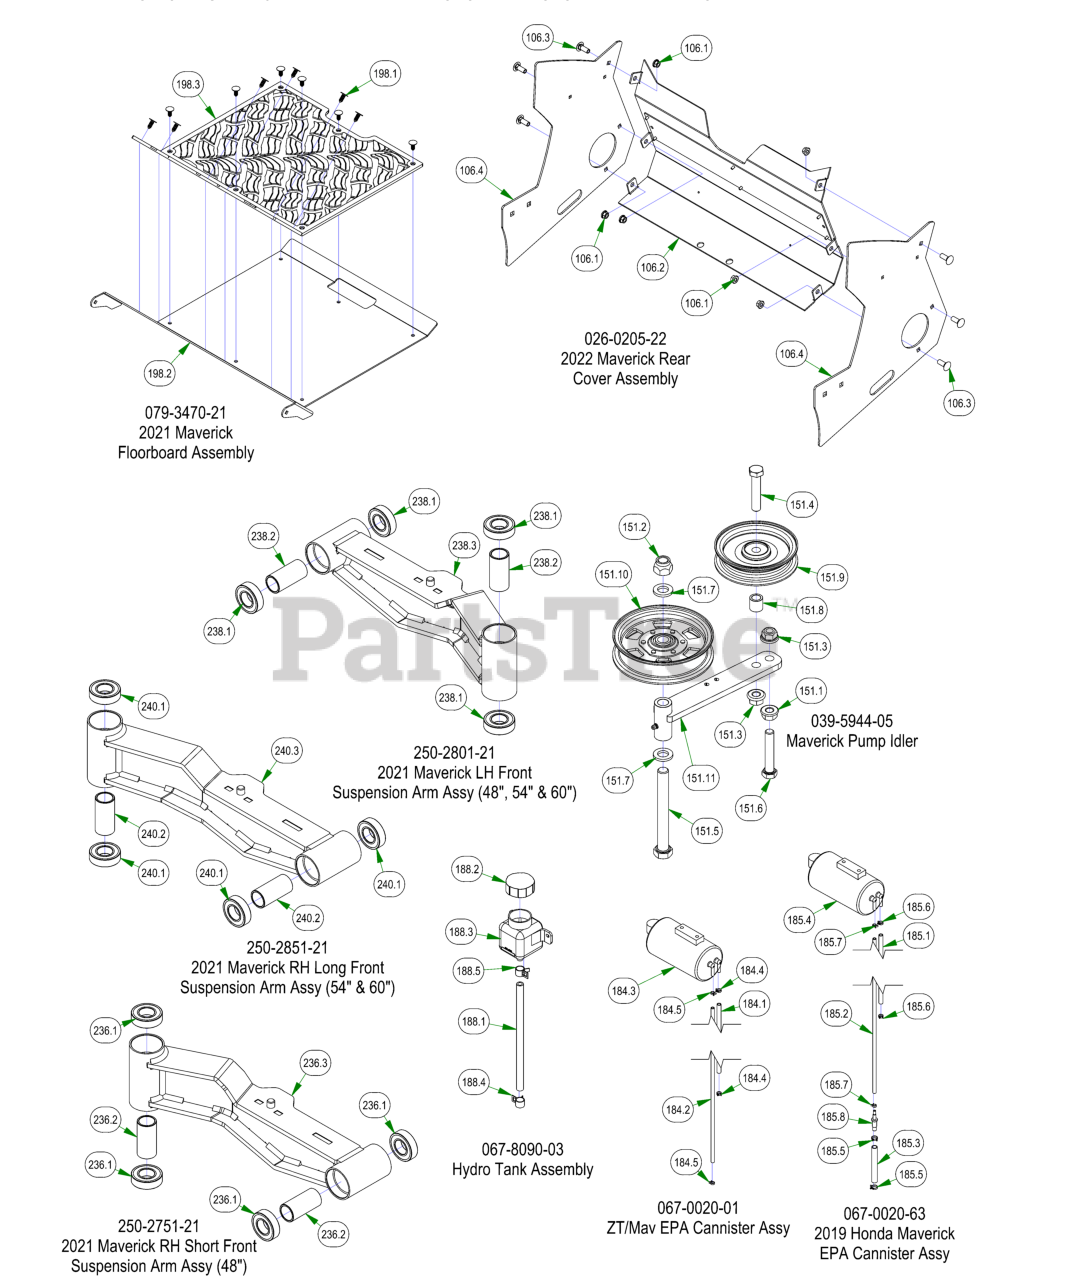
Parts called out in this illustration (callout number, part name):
106	2022 Maverick Rear Cover Assembly
106.1	5/16-18 NYLON INSERT FLANGE LOCKNUT ZINC
106.2	2021 Maverick Rear Cover Assembly
106.3	3/8-16 X 1 CARRIAGE BOLT (GR.5) ZINC
106.4	2022 Maverick Rear Cover Side Plate - Painted
151	Maverick Pump Idler
151.1	1/2-13 HEX SERRATED FLANGE NUT HARD/ZINC
151.2	5/8-11 NYLON INSERT LOCKNUT ZINC
151.3	1/2-13 NYLON INSERT FLANGE LOCKNUT ZINC
151.4	1/2-13 X 2-1/2 HEX CAP SCREW GR 5 ZINC
151.5	5/8-11 X 5-1/2 HEX CAP SCREW (GR.5) ZINC
151.6	1/2-13 X 2-3/4 HEX CAP SCREW (GR.5) ZINC
151.7	.635 ID X 1.120 OD X .140 THICK FLAT WASHER NYLON
151.8	.51 ID X .75 OD X .75 LGTH SOLID SPACER ZINC
151.9	4 3/4" Idler Pulley
151.10	5 3/4 Idler Pulley, 5/8 Bore
151.11	Deck Idler
184	ZT/Mav EPA Cannister Assy
184.1	1/4" Vinyl Tubing, 46" Long
184.2	3/16" Vinyl Tubing, 55" Long
184.3	Carbon Canister
184.4	3/16 Vinyl Clamp
184.5	3/16" Vinyl Hose Clamp
185	2019 Honda Maverick EPA Cannister Assy
185.1	1/4" Vinyl Tubing, 46" Long
185.2	3/16" Vinyl Tubing, 55" Long
185.3	3/8" PVC Tubing, 3.6" Long
185.4	Carbon Canister
185.5	5/16 Fuel Line Clamp
185.6	3/16 Vinyl Clamp
185.7	3/16" Vinyl Hose Clamp
185.8	3/8-1/4 Nylon Reducer
188	Hydro Tank Assembly
188.1	ZT/Maverick Hydro Tank Hose
188.2	Hydraulic Tank Cap
188.3	350ml Expansion Tank
188.4	3/8" Hose Clamp
188.5	1/2 Hose Clamp
198	2021 Maverick Floorboard Assembly
198.1	Ratchet Fastener
198.2	2018 Maverick Floorboard
198.3	2021 Maverick Floor Mat W/ Reaper Tread
236	2021 Maverick RH Short Front Suspension Arm Assy (48")
236.1	1641 BEARING W/2 CONTACT RUBBER SEALS
236.2	2016 Front Bearing Spacer
236.3	2021 Maverick I-Beam Front Arm RH Short Weldment - Painted
238	2021 Maverick LH Front Suspension Arm Assy (48", 54" & 60")
238.1	1641 BEARING W/2 CONTACT RUBBER SEALS
238.2	2016 Front Bearing Spacer
238.3	2021 Maverick I-Beam Front Arm LH Weldment - Painted
240	2021 Maverick RH Long Front Suspension Arm Assy (54" & 60")
240.1	1641 BEARING W/2 CONTACT RUBBER SEALS
240.2	2016 Front Bearing Spacer
240.3	2021 Maverick I-Beam Front Arm RH Long Weldment - Painted
